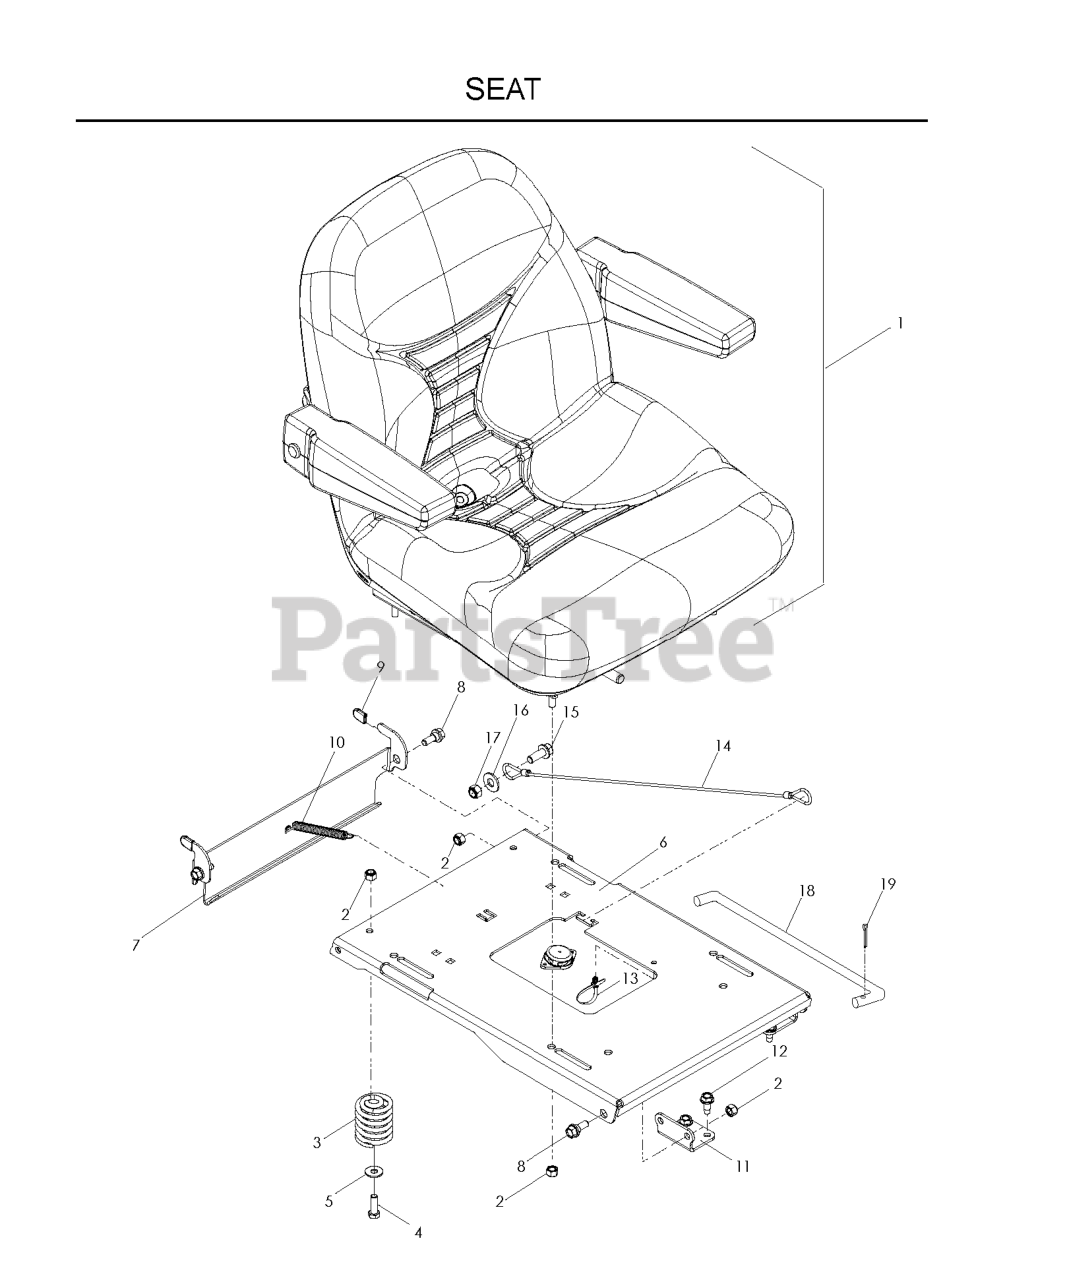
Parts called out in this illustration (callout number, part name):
1	SEAT
2	NUT 5/16 NYLOC
3	SPRING, SEAT
4	HCS 5/16C X 1
5	WASHER 5/16 FLAT
6	PAN, SEAT - BLACK
7	LATCH, SEAT - BLACK
8	SB 5/16-18 HEX HD GD5, BLK ZN
9	GRIP, VINYL, .09 X .495 X.75
11	PIVOT, SEAT PAN
12	BOLT 5/16-18 X 3/4
13	TIE WRAP, 8-3/8", W/CLIP
14	SEAT LANYARD
15	4CS 3/8C X 1 SERRATED HEAD
16	WASHER 3/8 FLAT
17	NUT 3/8-16 NYLOC
19	RP_COTTER PIN 1/8 X 3/4
20	SEAT SWITCH MILSCO
